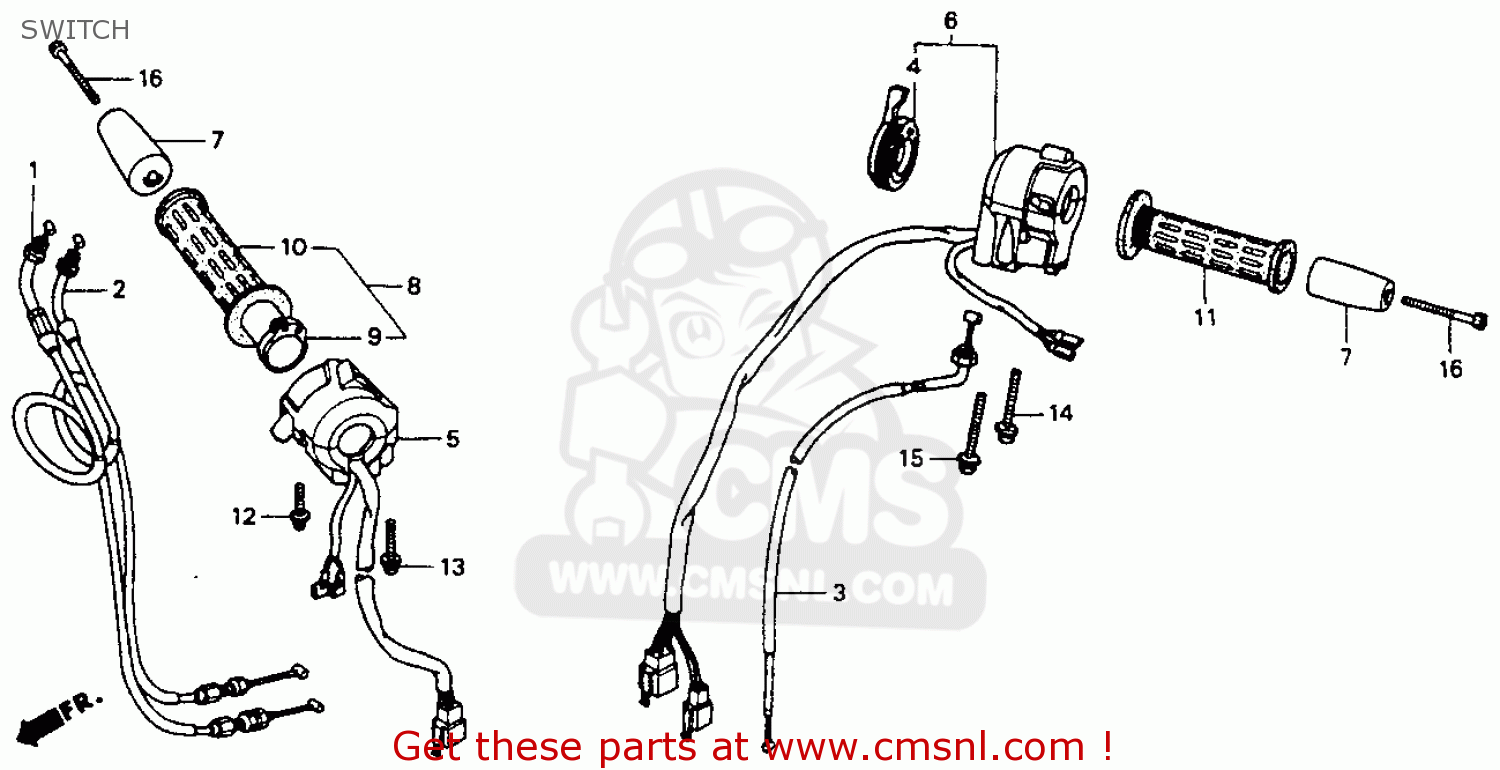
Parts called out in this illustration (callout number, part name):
1	CABLE COMP,A THRO
2	CABLE COMP,B THRO
3	CABLE COMP,CHOKE
4	LEVER,CHOKE
5	SW,ASSY ST KILL
6	SWITCH ASSY.,WINK
7	WEIGHT,STEERING H
9	PIPE,THROT.GRIP
10	GRIP,R.HANDLE
11	GRIP,L.HANDLE
12	SCREW WASHER 5X20
13	SCREW-WASHER,5X25
14	SCREW-WASHER,5X35
15	SCREW-WASHER,5X45
16	BOLT,SOCKET,8X65
